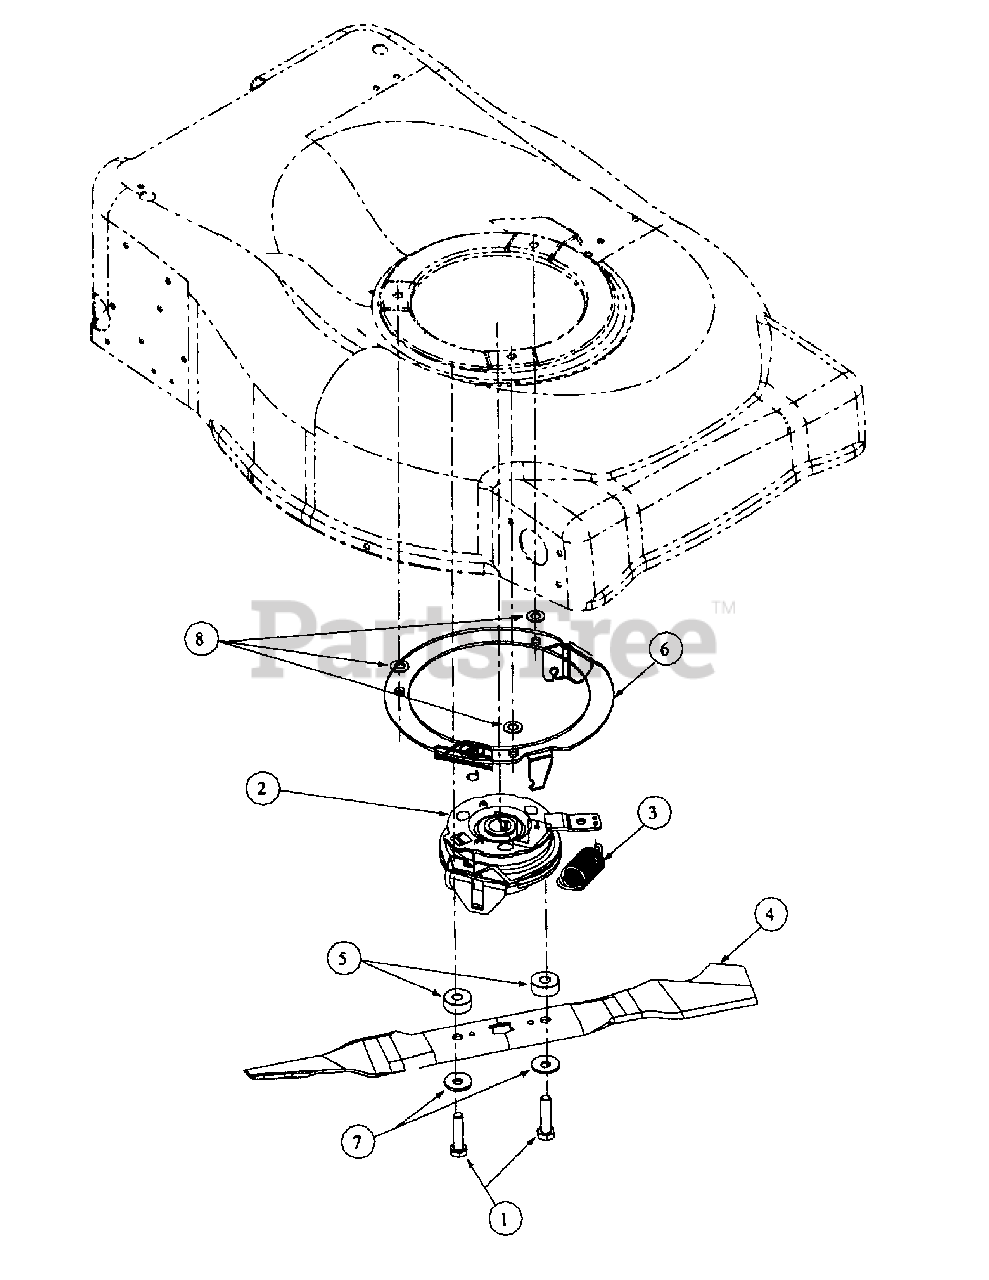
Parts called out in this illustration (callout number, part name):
1	Hex, Cap Screw, M10 x 1.5, 40mm
2	BBC, Complete, Clutch
3	Extension Spring, 1.100 OD x 2.795
4	21" Mulching Blade, with Star
5	Spacer, .412 x 1.125 x .44
6	Engine Mount Support Plate
7	Bell, Washer, .396 x 1.14 x .095
8	Flat Washer, 3/8 x .738 x .063
